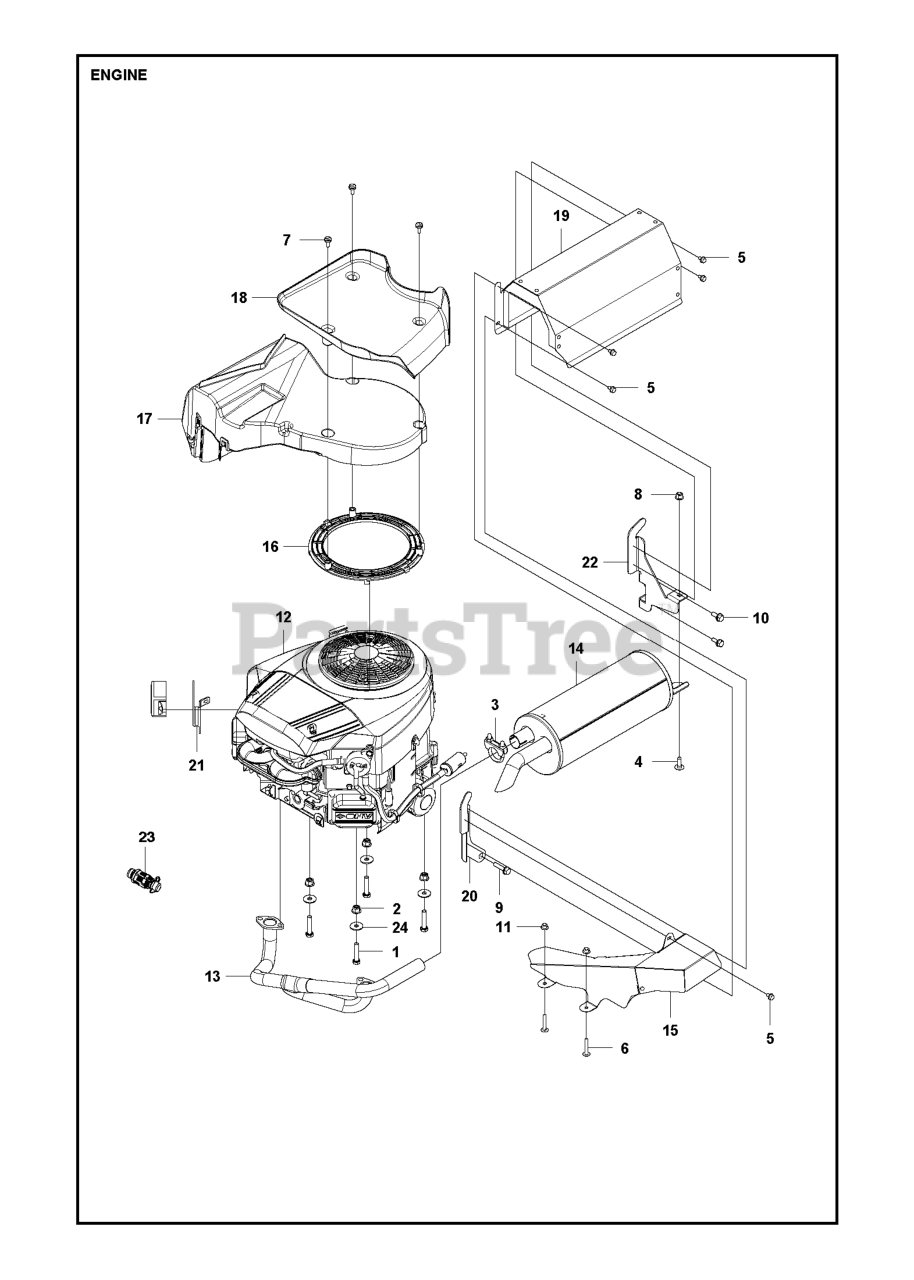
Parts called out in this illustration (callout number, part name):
2	NUT FLANGE
3	CLAMP ASSY EXHAUST
8	NUT FLANGE
9	SCREW EHHFM
11	NUT FLANGE
23	VALUE.OIL.DRAIN
